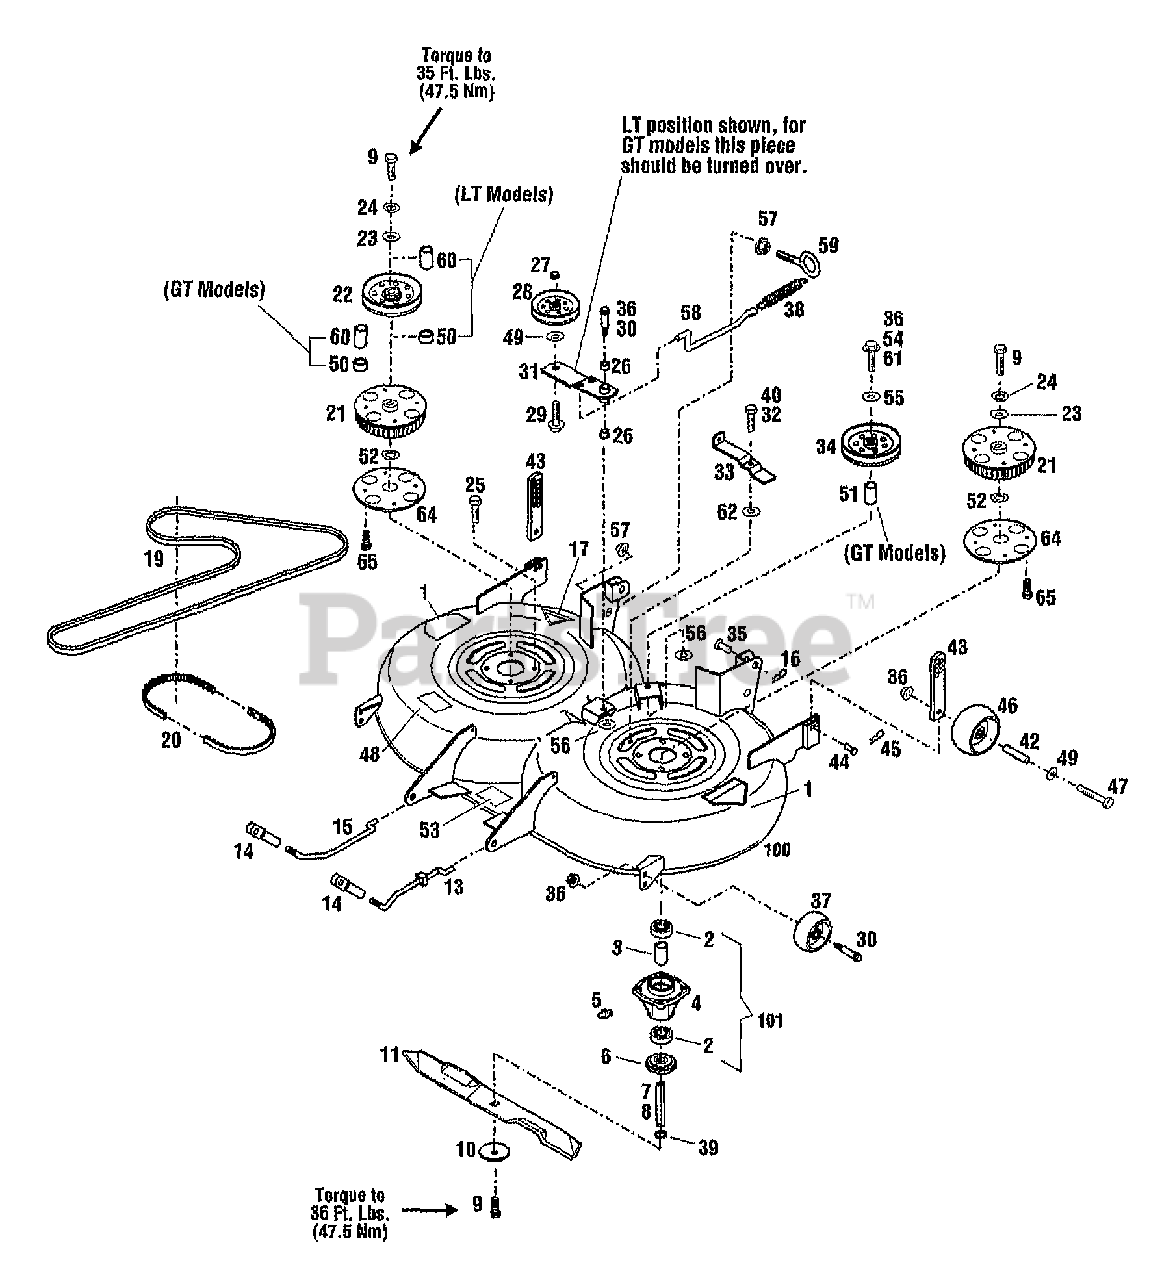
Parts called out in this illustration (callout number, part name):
1	DECAL-OPEI CAUTION
2	BEARING-BALL
4	HOUSING-SPINDLE
5	FITTING-GREASE 1/4-28X2.00
6	SPACER-BLADE
7	SHAFT-SPINDLE MED. H/T
8	SHAFT-LONG SPINDLE (RH)
9	SCR-HH 1/2-14X1.00
10	WASHER-BELLEVILLE
11	BLADE-MULCHING
13	ROD-LIFT FRONT LH
15	ROD-LIFT FRONT RH
16	PIN-HITCH .125X2.56 ZP
17	DECAL-OPEI
20	BELT-DRIVE 38"
21	SPROCKET-56T GRIVORY
22	ASSM-SHEAVE DRIVE
23	WASHER-1.37X.453X.179 ZP
24	WASHER-LK .438 ZP
25	SCR-HFLK 5/16-18X.75
26	BUSHING-.5X.5 NYLON FLNG
27	NUT-HFLK 3/8-16 ZP
28	PULLEY-IDLER
29	SCR-HH 3/8-16X1.75 G5 ZP
30	SCR-SHLDR 3/8-16
31	ASSM-IDLER ARM
32	SCR-HHC 5/16-18X.75 GR 5 ZP
33	BRKT-BELT TENSION ADJ
35	PIN-CLEVIS .625X2.25
36	NUT-LOCK 3/8-16
37	WHEEL-GAGE
38	SPRING
39	RING-RETAINING EXT .694 ID
40	NUT-TOP/LK 5/16-18 ZP
42	SPACER-GAGE WHEEL
43	LEVER-GAGE WHEEL ADJUST
44	PIN-CLEVIS .375 X .937 ZP
45	CLIP-HAIRPIN .07 DIA
46	WHEEL-GAGE
47	SCR-HH 3/8-16X3.5 G5 ZP
48	DECAL-BELT DRIVE
49	WASHER-.986X.437X.083 ZP
50	SPACER-1.25X.76X.50
51	SPACER
52	HARDENED WASHER
53	DECAL-LIFT ROD
54	SCR-HH 3/8-16X3.0 G5 ZP
55	WASHER-LK .375 @ DEPL
56	SPACER-SPECIAL 1/4
57	NUT-HFLK 5/16-18 ZP
58	ROD-IDLER
59	BOLT-EYE SC
60	SPACER-1.25X.77X.88
61	SCR-HH 3/8-16X1.75 G5 ZP
62	WASHER-.312 X .75
64	PLATE-SPROCKET COVER
65	SCR 1/4-20.75 TRI-PLASK
100	BASE-MOWER 38" W/DECALS
101	ASSM-MOWER SPINDLE
